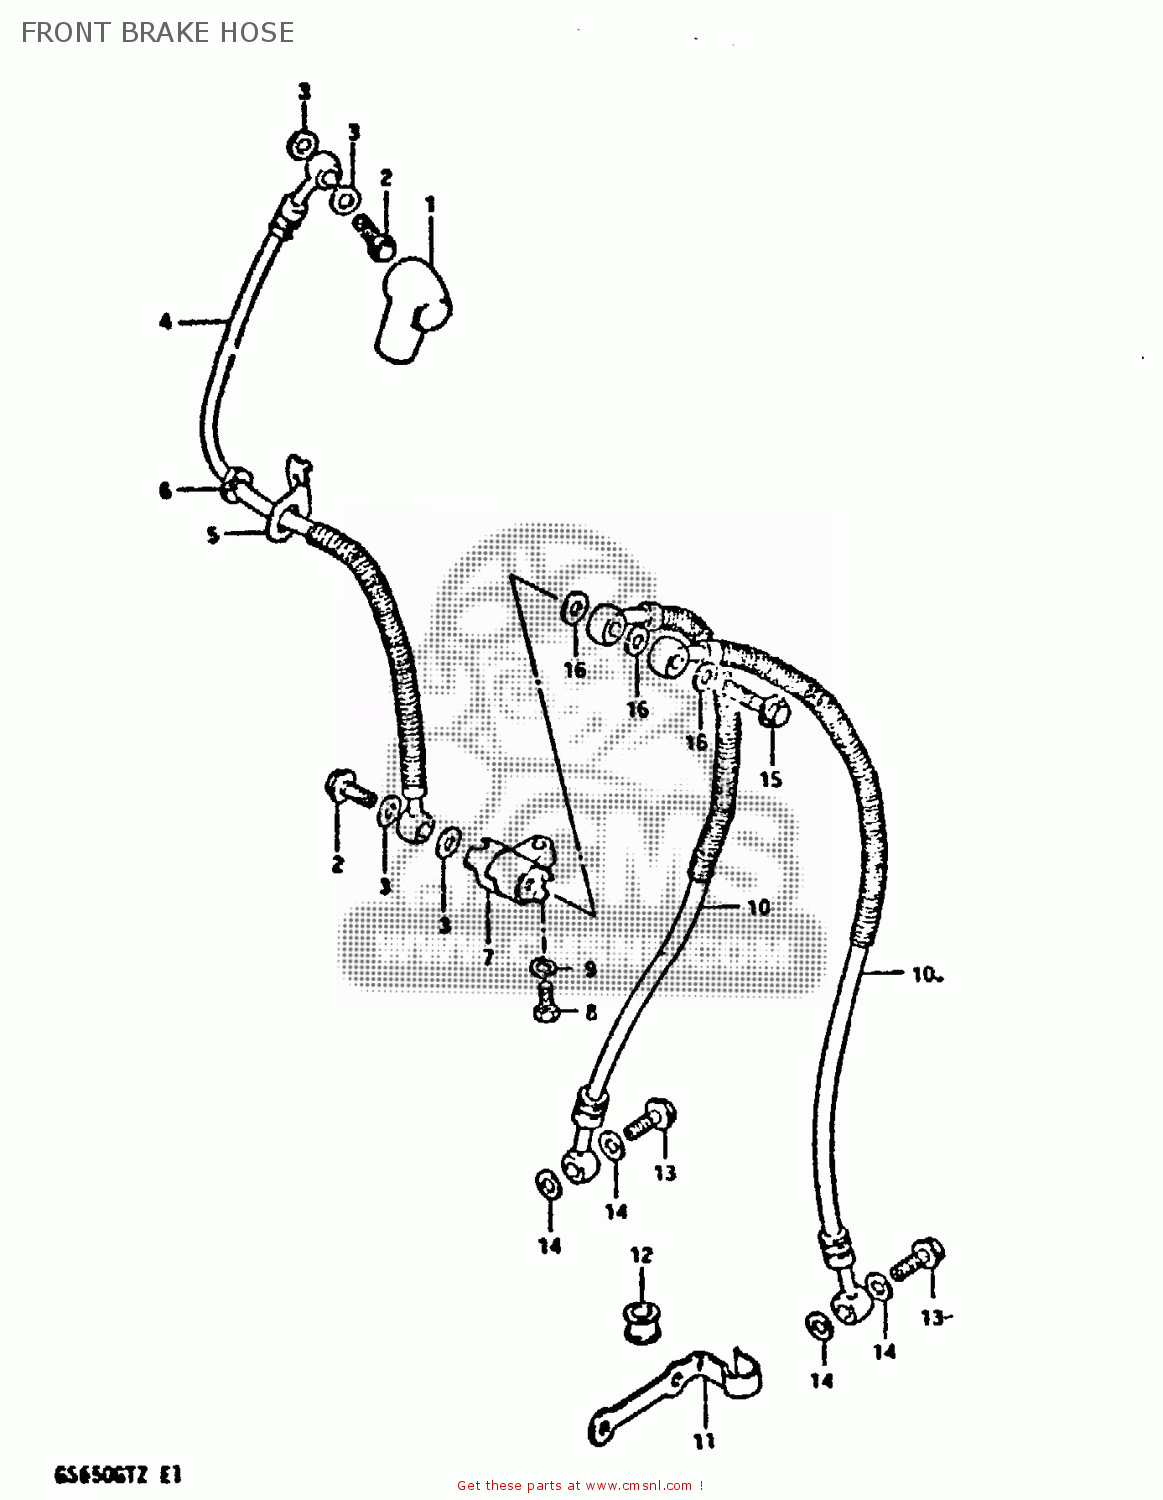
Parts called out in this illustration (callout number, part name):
1	BOOT,MASTER CYLINDER
2	BOLT,UNION
3	WASHER
4	HOSE,FRONT BRAKE
5	GUIDE,BRAKE HOSE
6	GROMMET
7	JOINT,BRAKE HOSE
8	BOLT
9	LOCK WASHER
10	HOSE,FRONT BRAKE
11	GUIDE,BRAKE HOSE NO.2
12	BUSH,BRAKE HOSE GUIDE,NO.2
13	BOLT,UNION
14	WASHER
15	BOLT,UNION
16	WASHER
